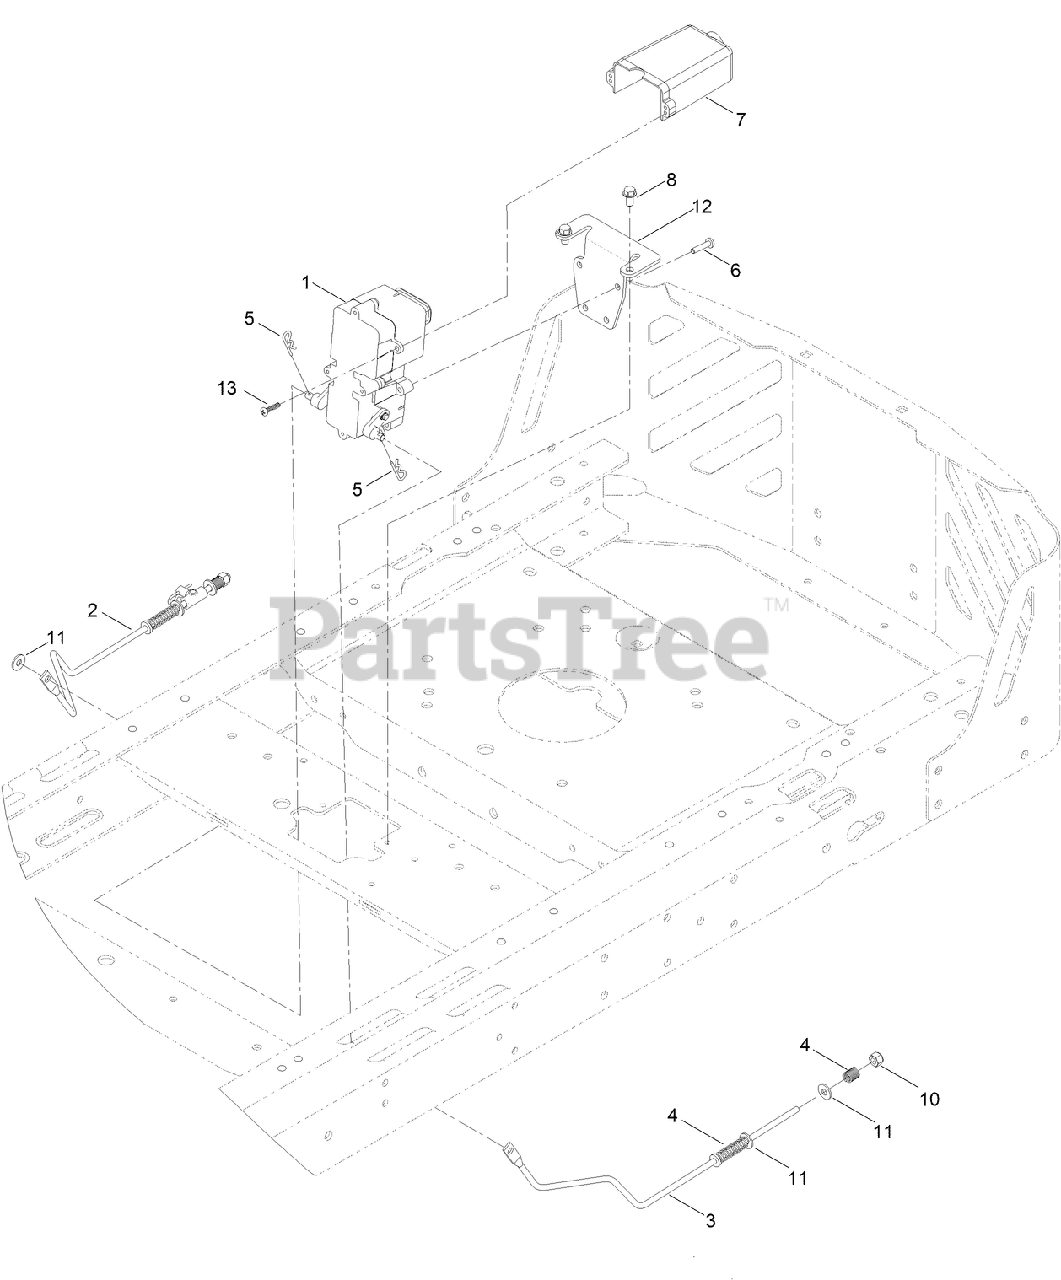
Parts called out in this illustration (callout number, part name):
2	ROD-BRAKE, WIDE (RH)
3	ROD-BRAKE, WIDE (LH)
4	SPRING-COMPRESSION
6	SCREW-PPH
8	SCREW-HWH
10	NUT-LOCK, NI
11	WASHER
12	BRACKET-MOUNT, BRAKE
13	SCREW-PPH
